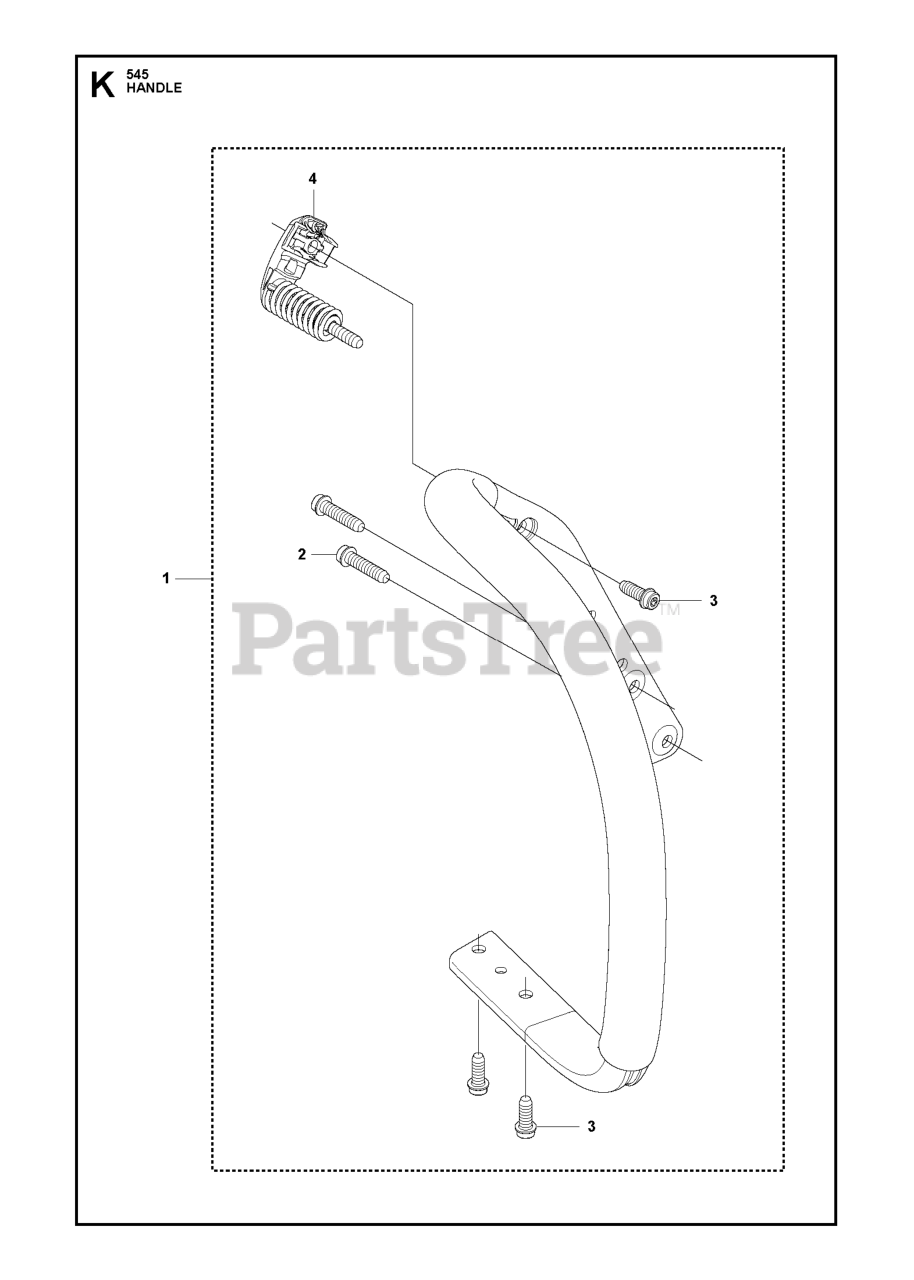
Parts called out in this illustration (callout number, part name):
1	FRONT HANDLE
3	SCREW ITXSCFT PL6X16 T27 10.9
4	ANTIVIBRATION ELEMENT
